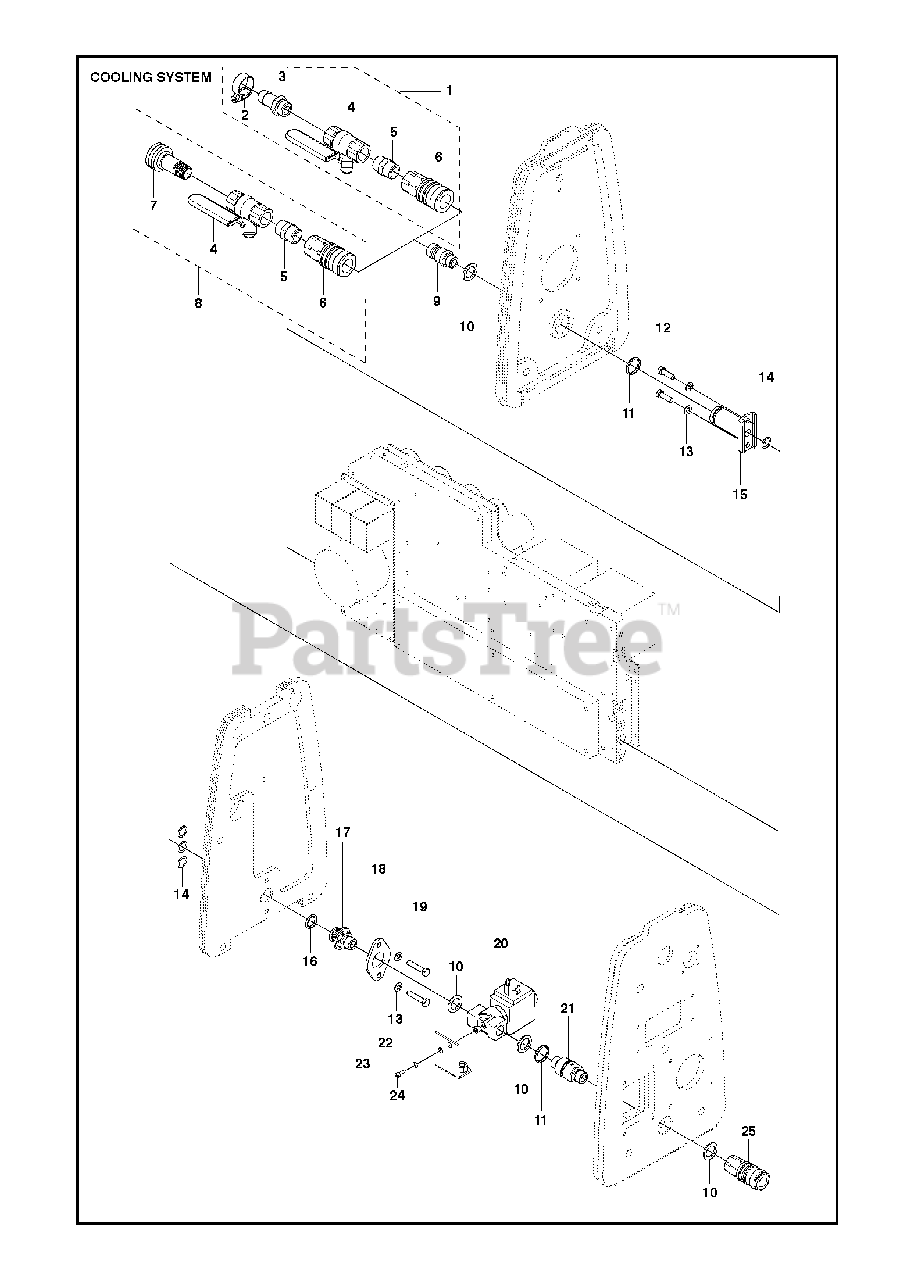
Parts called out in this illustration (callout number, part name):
1	VALVE ASSYIncl. 2 - 6
8	VALVE ASSYIncl. 4 - 7
10	SEALING WASHER
13	WASHER
19	SCREW IHSCM
